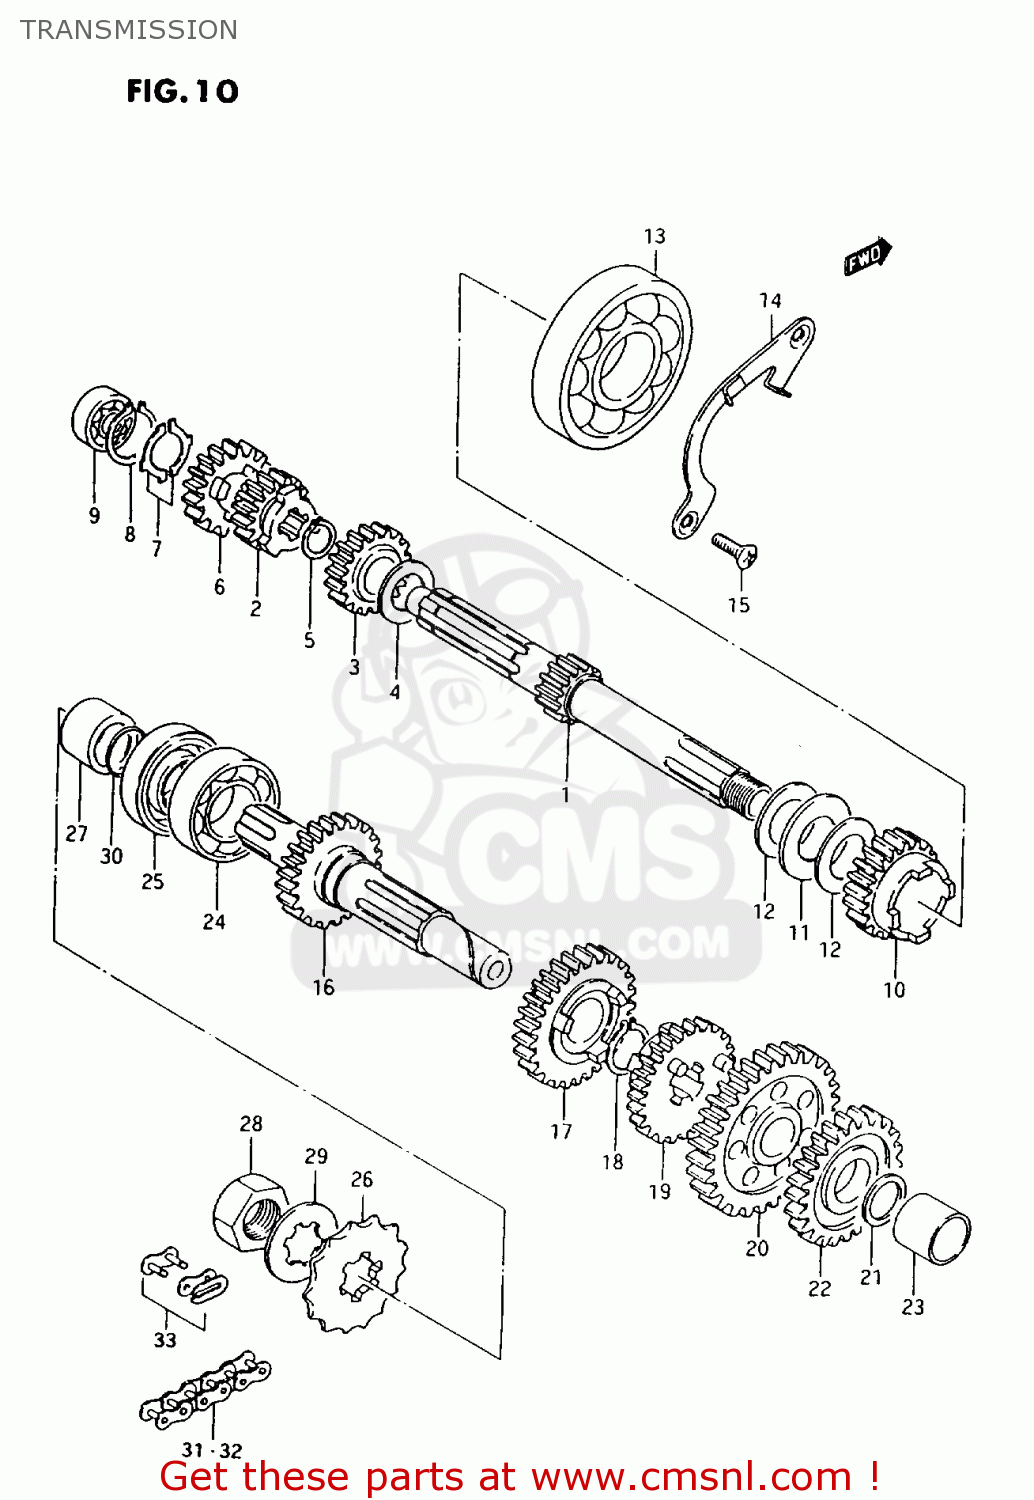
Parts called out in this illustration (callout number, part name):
1	SHAFT,COUNTER
2	GEAR,SECOND DRIVE
3	GEAR, 3RD DRIVE (NT:18)
4	WASHER
5	CIRCLIP
6	GEAR, 4TH DRIVE (NT:22)
7	RING
8	RING,SNAP
9	BEARING(12X28X8)
10	GEAR,KICK STARTER DRIVEN
11	BEARING(21X32X2.85)
12	WASHER(21X30X0.8)
13	BEARING(30X62X10)
14	RETAINER,CNTR SHAFT BEARING
15	SCREW
16	DRIVESHAFT (NT:21)
17	GEAR, 2ND DRIVEN (NT:27)
18	CIRCLIP
19	GEAR, 3RD DRIVEN (NT:23)
20	GEAR,FIRST DRIVEN
21	WASHER
22	GEAR,KICK STARTER IDLE
23	BUSH
24	BEARING(20X47X14)
25	SEAL,OIL(25X40X9)
26	SPROCKET,ENGINE(NT:14)
27	SPACER(20X25X15.5)
28	NUT
29	WASHER,LOCK
30	O RING(D:1,ID:19.5)
31	CHAIN,DRIVE(126L)
32	CHAIN,DRIVE
33	JOINT(RK)
